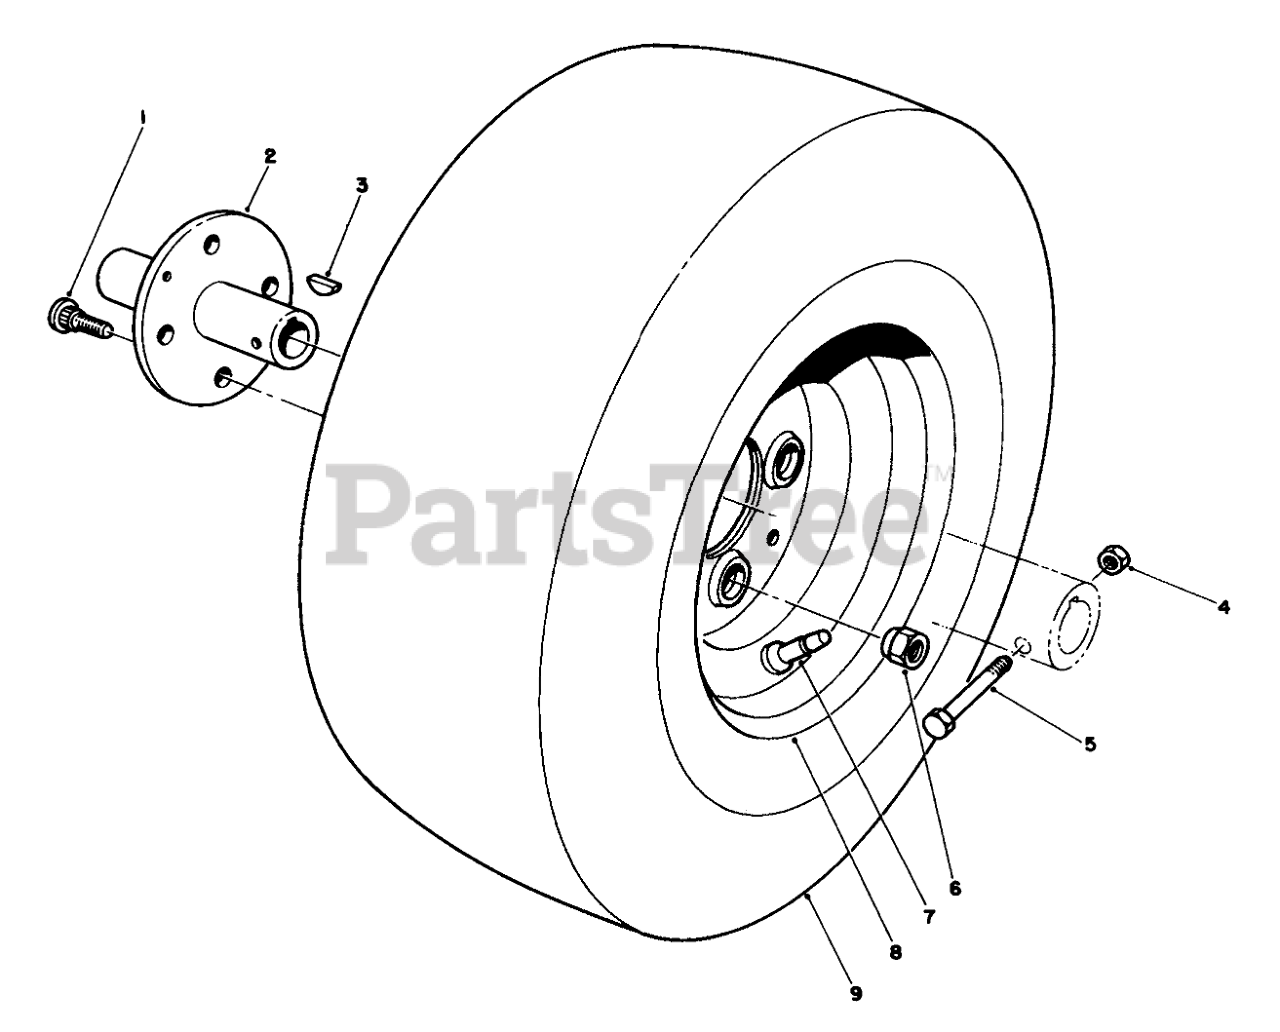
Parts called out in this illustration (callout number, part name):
1	1/2-20X1.25 BOLT
2	WHEEL HUB
3	KEY-WOODRUFF
4	NUT-LOCK, NI
5	SCREW-HH
6	NUT-LUG
7	STEM-VALVE
9	TIRE-4-Ply
